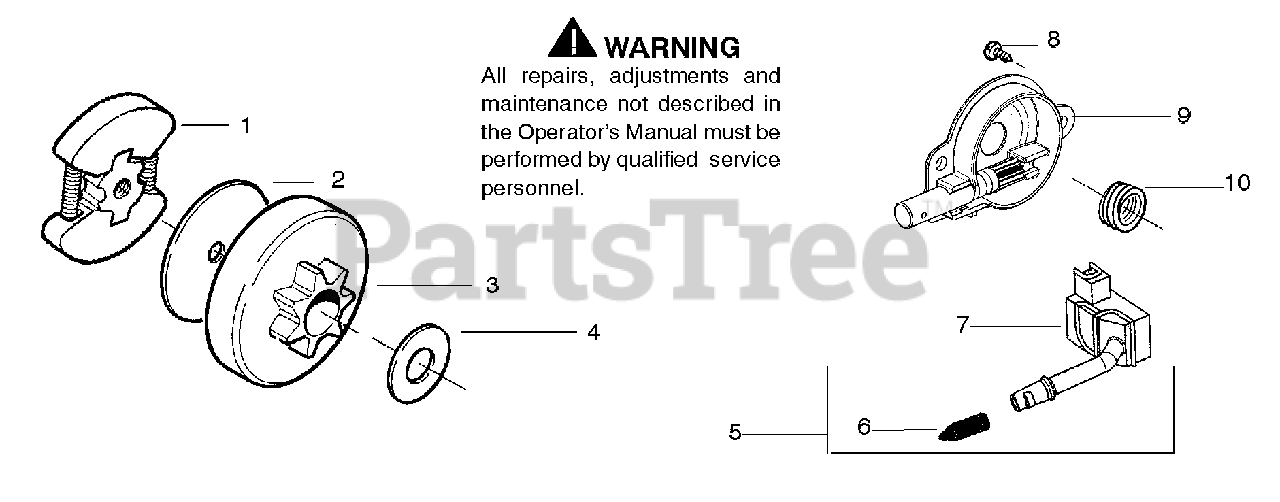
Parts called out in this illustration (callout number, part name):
1	Assy-Clutch
2	Washer-Clutch
3	Assy-Clutch Drum w/Bearing
4	Washer-Thrust
5	Assy-Oil Pickup and screen
6	Filter- Oil
7	Assy-Pickup
9	Assy- Oil Pump
10	Worm Gear - Oil Pump
